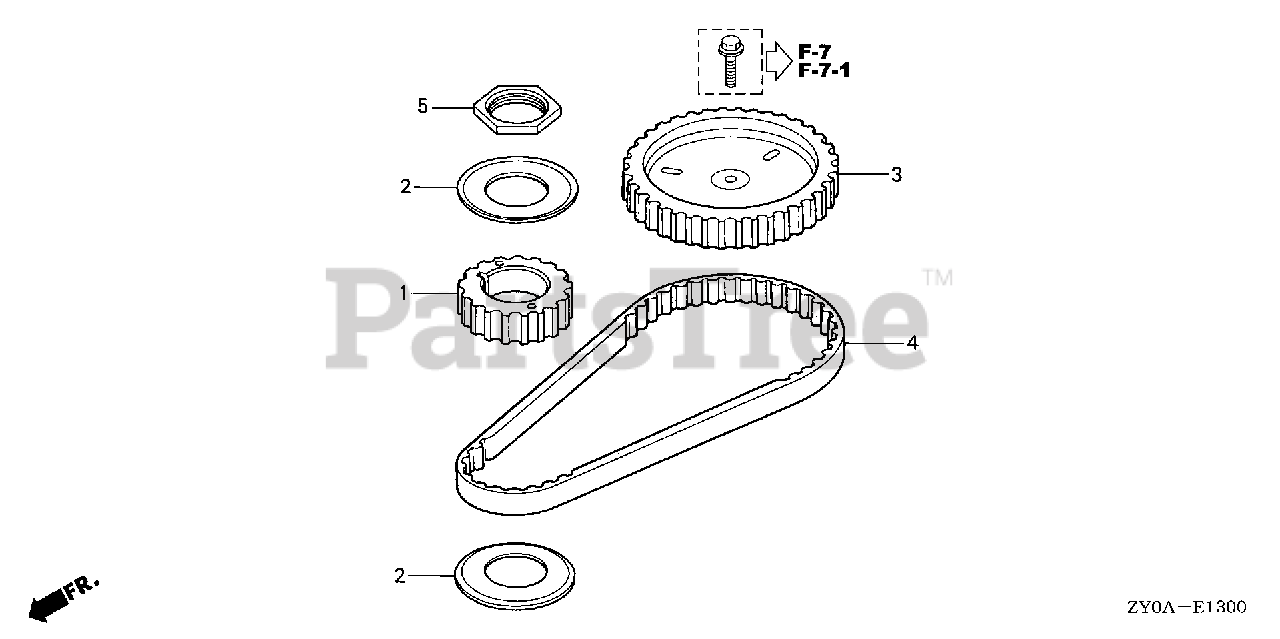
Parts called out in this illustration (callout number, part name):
1	PULLEY, TIMING
2	FLANGE, TIMING PULLEY
3	PULLEY, CAMSHAFT
4	BELT, TIMING (71RU13 B-333)
5	NUT, LOCK (30MM)
